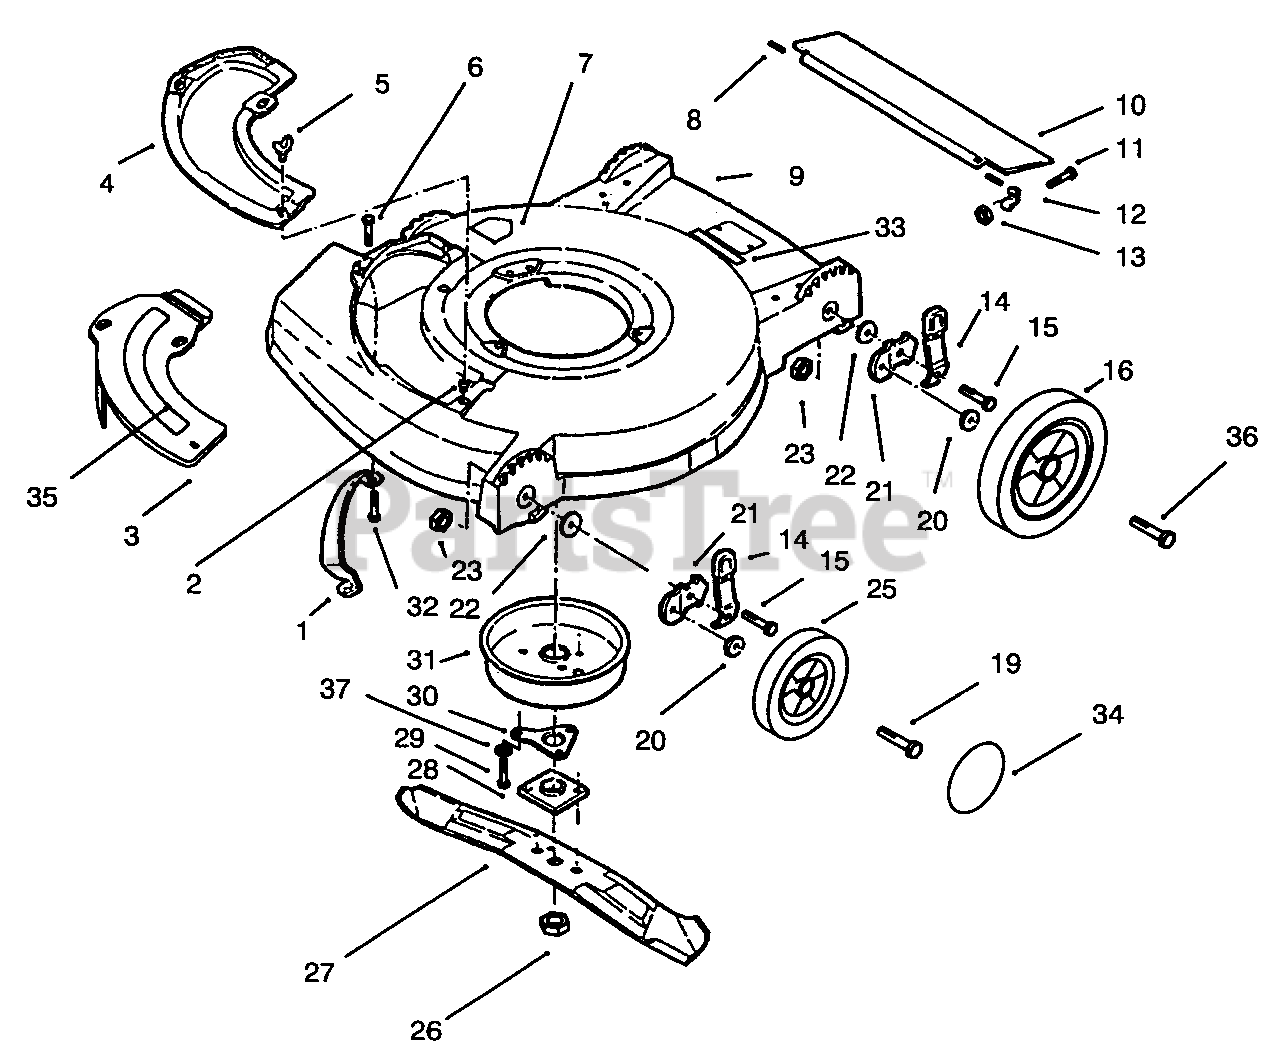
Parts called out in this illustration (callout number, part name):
1	Toe Bar
2	Grommet
3	Cover-Plate, Mulch (Incl. Ref.#35)
4	Cover Plate
5	Nut-Wing
6	Screw-Plate Mounting
7	Decal-Danger (Englsh)
9	Housing Assembly (Incl. Ref. # 2, 7 & 33)
10	Shield-Trailing
11	Screw-Trailing Shield
14	Knob and Spring Assembly
15	Bolt-Shoulder
16	Wheel-Rear 8"
19	Bolt-Wheel 6"
21	Bracket-Wheel Ht. Adjust
22	Washer-Wheel Ht. Adjust
23	Nut-Wheel Ht. Adjust
25	Wheel-Front 6"
26	Nut
27	Blade 19"
28	Collar and Plate Assembly
29	Screw-Muff. to Muff. Plate
30	Support-Crankshaft
31	Muffler Cover Assembly
33	Decal-Warning (English)
36	Bolt-Wheel 8"
37	Washer-Flat
